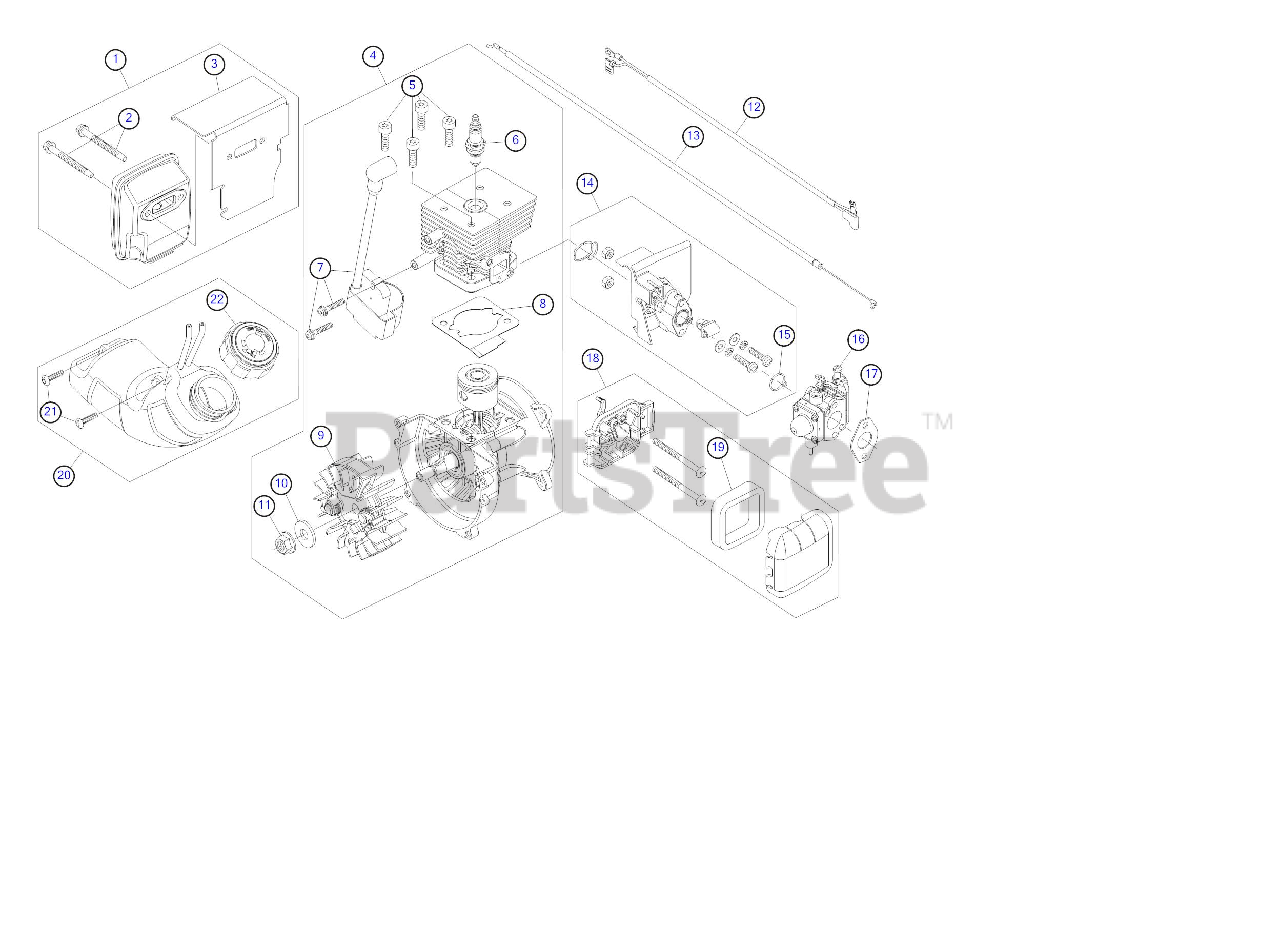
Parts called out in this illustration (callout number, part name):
1	Muffler Assembly (Incl. 2 & 3)
2	Muffler Screws
3	Muffler Gasket
4	Shortblock Assembly (Incl. 5 - 11)
6	Spark Plug
7	Module Assembly
8	Cylinder Gasket
9	Flywheel Assembly
13	Throttle Cable
14	Insulator Assembly (Incl. 15)
15	Insulator O-Ring
16	Carburetor Assembly (Incl. 17)
17	Carburetor Gasket
18	Air Cleaner Assembly (Incl. 19)
19	Air Filter
20	Fuel Tank Assembly (Incl. 21 & 22)
